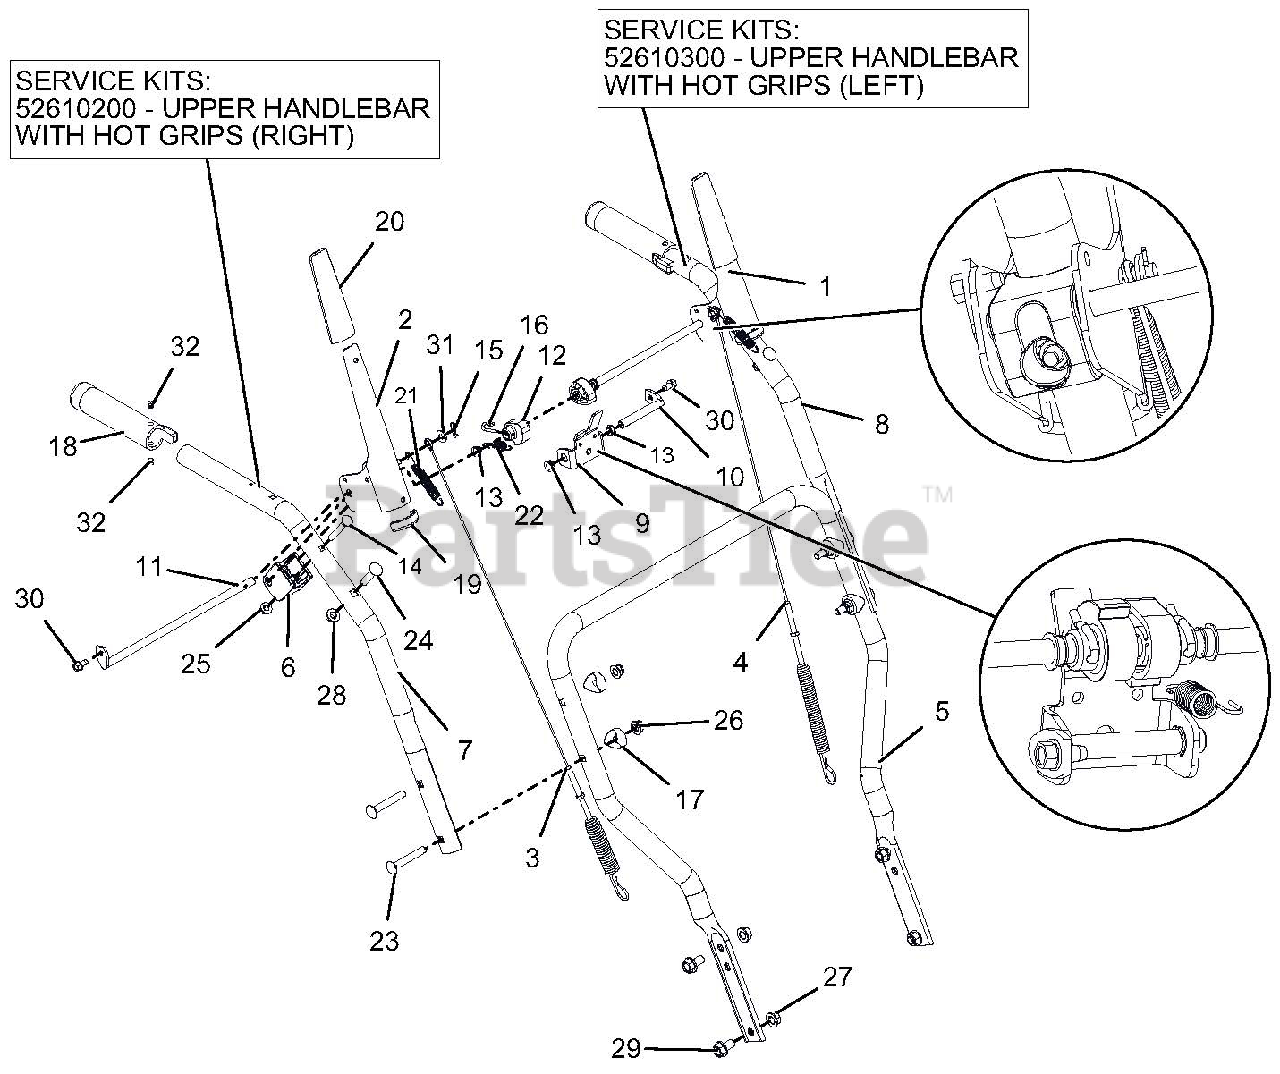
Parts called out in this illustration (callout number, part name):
1	LEVER, CLUTCH-LH
2	LEVER, CLUTCH-RH
3	CABLE, AUGER (DELUXE & PRO)
4	CABLE, UPPER TRACTION
5	HANDLEBAR, LOWER
6	BLOCK, CLUTCH PADDLE
7	HANDLEBAR, UPPER - RH
7	HANDLEBAR, UPPER RH W/HW
8	HANDLEBAR, UPPER - LH
8	HANDLEBAR, UPPER LH W/HW
9	BRACKET, INTERLOCK ARM
10	ROD, PIVOT - INTERLOCK
11	ROD, PADDLE MOUNT - PRO
12	CAM, INTERLOCK
13	BUSHING, POLYLINER-.38 SNAPIN
14	BLT-RDHDXLSQNK .25-20X2.0 G5YZ
15	PIN-HAIR INT .06X.18X.77
16	PIN, SPRING CLIP
17	SPACER, HANDLEBAR
18	HEATED GRIP, MAGURA
19	EDGING, CLUTCH PADDLE - 2.00"
20	CLUTCH PADDLE SLEEVE - GRAY
21	SPRING, EXTENSION
22	SPRING-EXT .047X.438X1.45
23	@BLT-RDHDSQNK .31-18X2.25 G5YZ
24	@BLT-RDHDSQNK .31-18X1.50 G5YZ
25	@NUT-LK-CTR-FLG .25-20 YWZC
26	@NUT-LK-NYL-FLG .31-18 YWZC
27	@NUT-LK-TOP-FLG .38-16 YWZC
28	@NUT-LK-TOP-FLG .31-18 YWZC
29	BLT-SERHFWH .38-16X.75 YWZC
30	SCR-TAP .25-20X.50 HWH TR YWZ
31	@WSHR-FL-STL.281X.62X.065 YWZC
32	RVT-POP #43 .125X.313 STL ZINC
